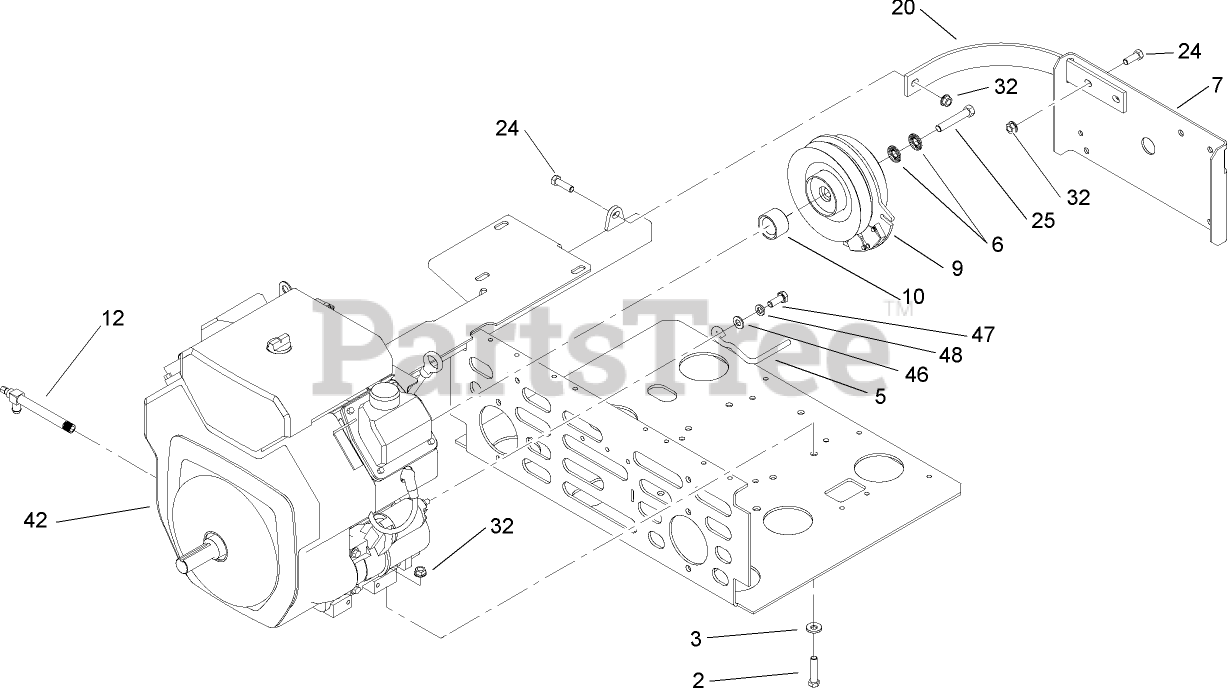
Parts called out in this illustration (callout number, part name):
2	SCREW-HH
3	WASHER-BELLEVILLE
5	ROD-BELT
6	WASHER-SPRING
7	GUARD-CLUTCH
9	CLUTCH
10	SPACER-CLUTCH
12	VALVE-OIL DRAIN, LONG
20	STRAP-GUARD
24	SCREW-HH
25	SCREW-HH
32	NUT-HHF, WHIZ
46	WASHER-FLAT
47	SCREW-HH
48	WASHER-BELLEVILLE
